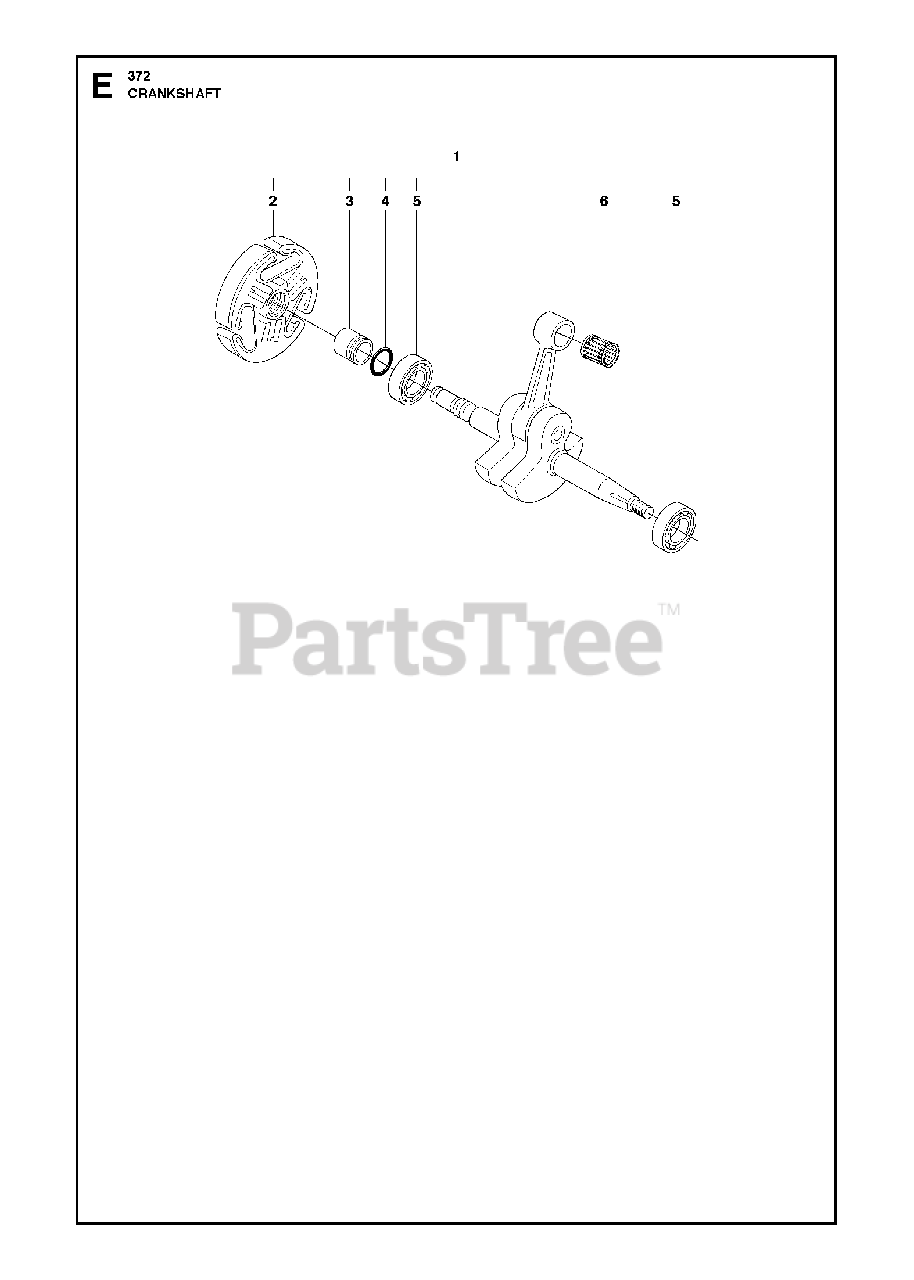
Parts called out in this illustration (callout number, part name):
1	CRANKSHAFT COMPLETE
2	CLUTCH
3	SLEEVE
4	O-RING
5	BALL BEARING-6202-C3 SKF
6	SUPPORT BUSHING
